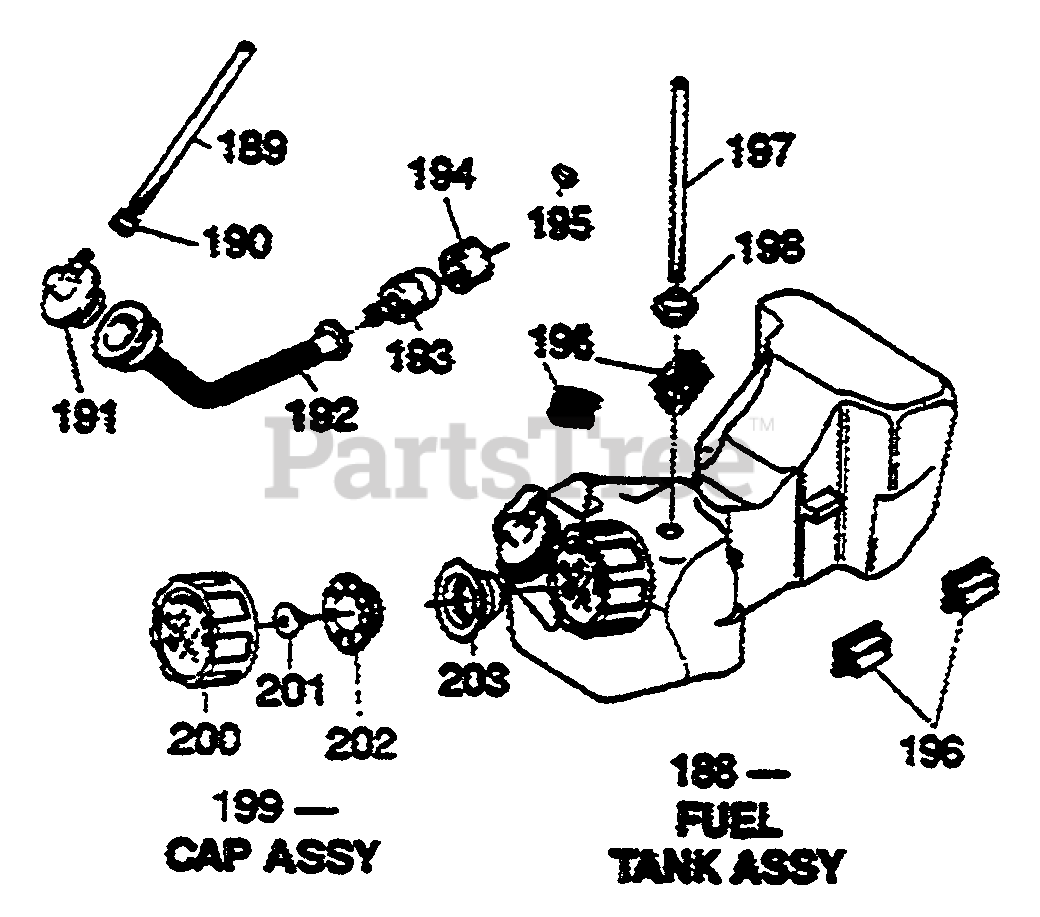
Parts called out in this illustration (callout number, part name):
188	FUEL TANK ASSY
189	TUBE, FUEL
192	HOSE, SUCTION
193	FILTER,FUEL
197	TUBE,FUEL
199	TANK CAP ASSY
200	CAP, TANK
201	VALVE, BREATHER
